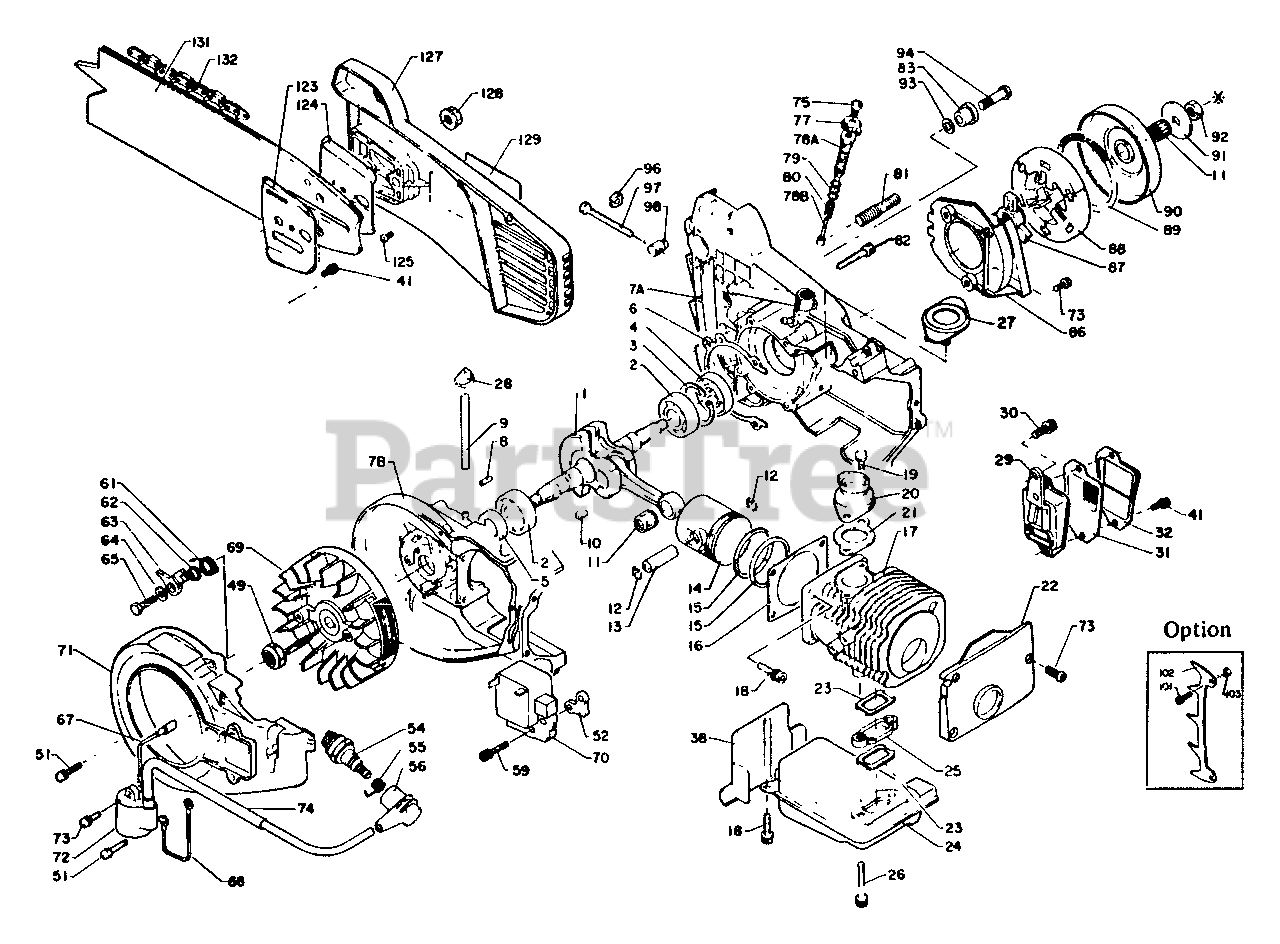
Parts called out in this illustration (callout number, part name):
1	CRANKSHAFT ASSY
2	BEARING, BALL - 6202
3	RING, RETAINING - 35
4	SEAL, OIL
5	SEAL, OIL
6	GASKET, CRANKCASE
7	CRANKCASE KIT
7A	CRANKCASE KIT
7B	CRANKCASE KIT
8	PIN - LOCATING
9	PIPE - 3X6X75 -- BLACK
11	BEARING, NEEDLE
12	RING, RETAINING - 8
13	PIN, PISTON
14	PISTON
15	RING, PISTON
16	GASKET, CYLINDER
17	CYLINDER
18	SCREW - 5X20
19	SCREW - 5X10
20	ADAPTOR, INTAKE
21	GASKET, INTAKE
22	COVER, CYLINDER
23	GASKET, EXHAUST
24	MUFFLER
25	BAFFLE, MUFFLER
26	SCREW - 5X40
30	SCREW - 5X14
31	SCREEN, SPARK ARRESTOR
32	GUIDE, EXHAUST
38	INSULATOR
41	SCREW - 4X10
51	SCREW - 4X20
54	SPARK PLUG -- BPM-6A
55	TERMINAL, SPARK PLUG CAP
56	CAP, SPARK PLUG
59	SCREW - 4X22
61	SPRING, RETURN
62	SPACER
63	PAWL, STARTER
64	WASHER - 5
65	BOLT - 5X20
67	LEAD
68	LEAD - GROUND
69	FLYWHEEL
70	COIL, IGNITION
71	SHIELD, FAN
72	COIL, IGNITION
73	SCREW - 4X14
74	TUBE
75	SCREW - 5X10
77	LOCKWASHER
78	AUTO-OILER ASSY
78A	AUTO-OILER ASSY
78B	AUTO-OILER ASSY
79	O-RING - 5
81	STUD, GUIDE BAR
82	SCREW - 5X30
83	CHAIN CATCHER KIT
86	SEAL, DUST
87	HUB, CLUTCH
88	SHOE, CLUTCH
89	SPRING, CLUTCH
90	DRUM, CLUTCH
91	WASHER, CLUTCH
92	LOCKNUT
93	WASHER - 5
94	SCREW - 5X25
97	SCREW, TENSIONER
98	TENSIONER, CHAIN
101	SCREW - 5X12
102	SPIKE
103	NUT - 5
123	PLATE, GUIDE - INNER
124	PLATE, GUIDE - OUTER
125	SCREW - 3X6
127	GUARD, SPROCKET
128	NUT - FLANGE
129	LABEL - ECHO
131	GUIDE BAR
132	CHAIN, SAW
